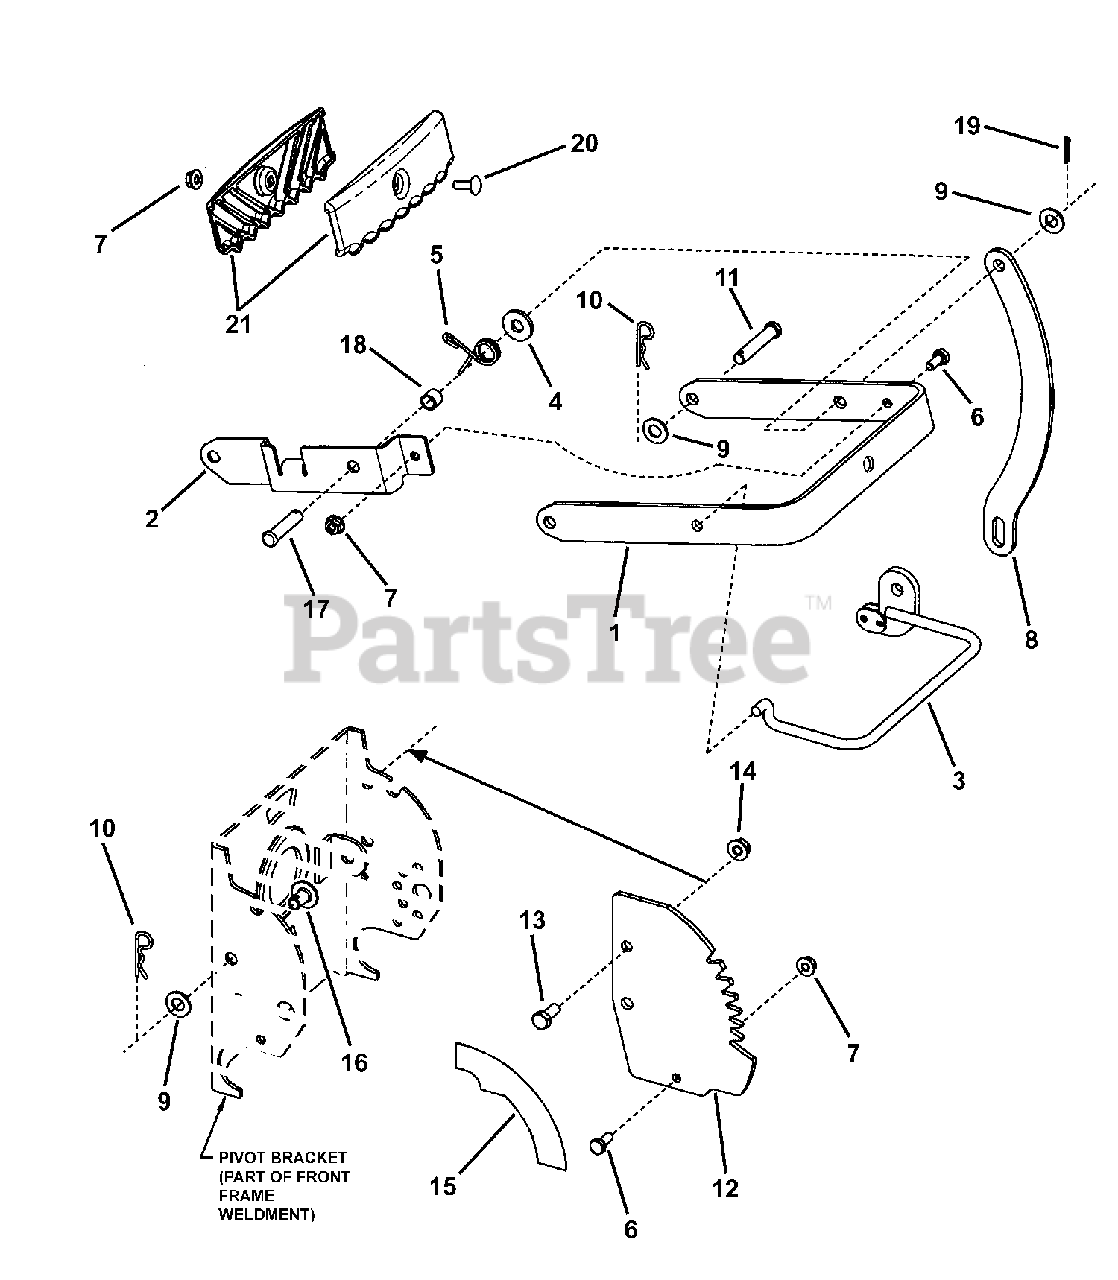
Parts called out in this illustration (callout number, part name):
1	HANDLE, Deck Lift
2	BRACKET, Pivot Support
3	WELDMENT, Deck Lift Handle
4	WASHER - Slipper
5	SPRING, Torsion
6	SCREW, 1/4-20 x 5/8" Hex Head Cap, GR 5
7	NUT, 1/4-20 Hex Flange Lock
8	BAR, Deck Lift
9	WASHER, 3/8" SAE Flat
10	HAIR PIN, 3/32 x 1-1/2"
11	PIN, 3/8 x 2" Clevis
12	DETENT, Lift Handle
13	SCREW, 5/16-18 x 3/4" Hex Head Cap, GR 5
14	NUT, 5/16-18 Hex Flange Lock, GR 5
15	DECAL, Deck Position
16	PIN, 3/8 x 1/2" Large Head Clevis
17	PIN, 3/8 x 1-5/8" Clevis
18	SPACER, Deck Lift
19	PIN, 3/32 x 3/4" Cotter
20	BOLT, 1/4-20 x 3/4" Short Neck Carriage, GR 5
21	GRIP, Deck Lift
